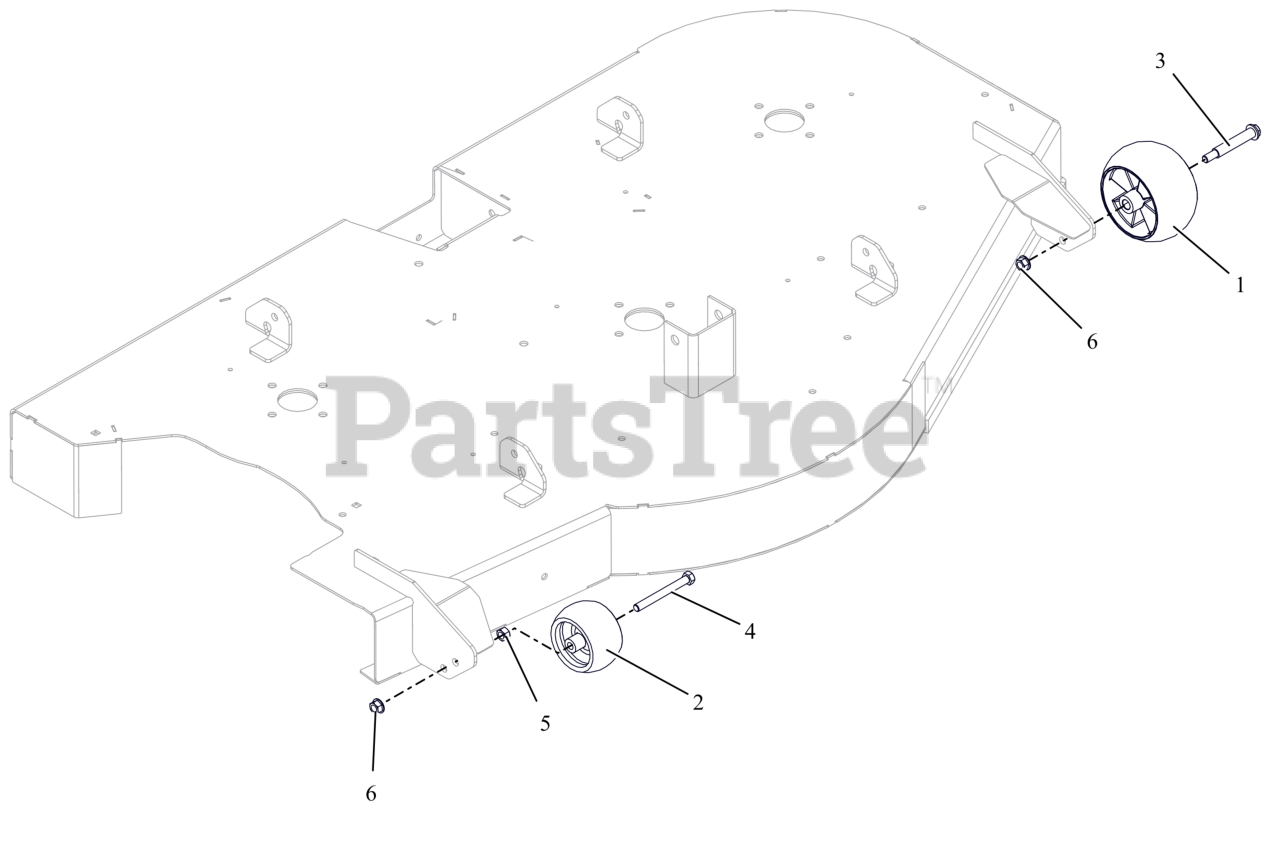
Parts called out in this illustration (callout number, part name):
1	ANTI-SCALP WHEEL - 5X OS
3	BLT-SHLDR .38-16X2.50 HWH G5
4	BLT, HEX .38-16X3.50 G5 ZCC
5	NUT-STD .375-16 G2 ZCC
6	NUT-LK-CTR-FLG .375-16 GF ZCC
